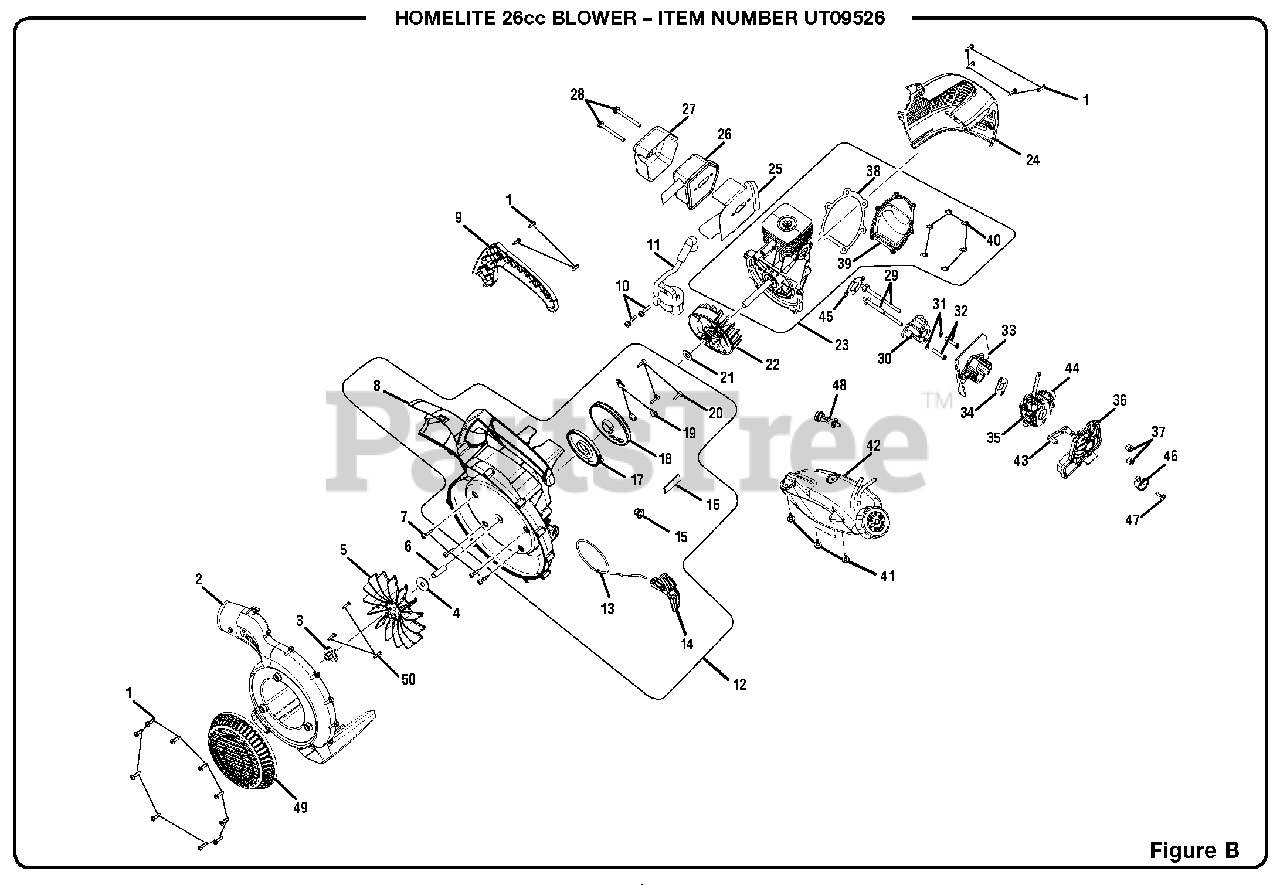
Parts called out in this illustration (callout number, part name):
1	Screw (M4 x 18 mm, T20 Torx Hd.)
2	Outer Volute
3	Blower Fan Nut
7	Screw (M4 x 17 mm,T20 Torx Hd. T.F.)
8	Inner Volute
9	Handle Cover
10	Screw (M4 x 19 mm, T20 Torx Pan Hd. T.F.)
11	Ignition Module
12	Lower Housing w/Starter Assembly
13	Starter Rope (42 in.)
14	Starter Grip
17	Spring & Container
18	Starter Pulley
19	Pulley Retainer
20	Screw (M4 x 14 mm, T20 Torx Hd. T.F.)
23	Short Block Assembly
24	Engine Cover w/Heat Shield
25	Muffler Gasket
26	Muffler Assembly
27	Muffler Heat Shield
28	Bolt (10-24 x 2-1/8 in.)
29	Bolt (M5 x 62 mm)
32	Screw (M5 x 25 mm, T20 Torx Hd.)
34	Heat Dam Gasket
35	Carburetor
36	Air Box Base
37	Hex Nut (M5)
38	Crankcase Cover Gasket
39	Crankcase Cover
40	Screw (M4 x 12 mm, T20 Torx Hd.)
41	Screw (M4 x 14 mm, T25 Torx Truss Hd.)
42	Fuel Tank Assembly w/Cap
43	Choke Lever
44	Primer Bulb
45	Intake Gasket
46	Choke Cover
47	Screw (M4 x 12 mm, T20 Torx Pan Hd.)
48	Fuel Filter
49	Blower Door
50	Screws (10-14 x 3/4 in., T25 Torx Pan Hd. T.F.)
